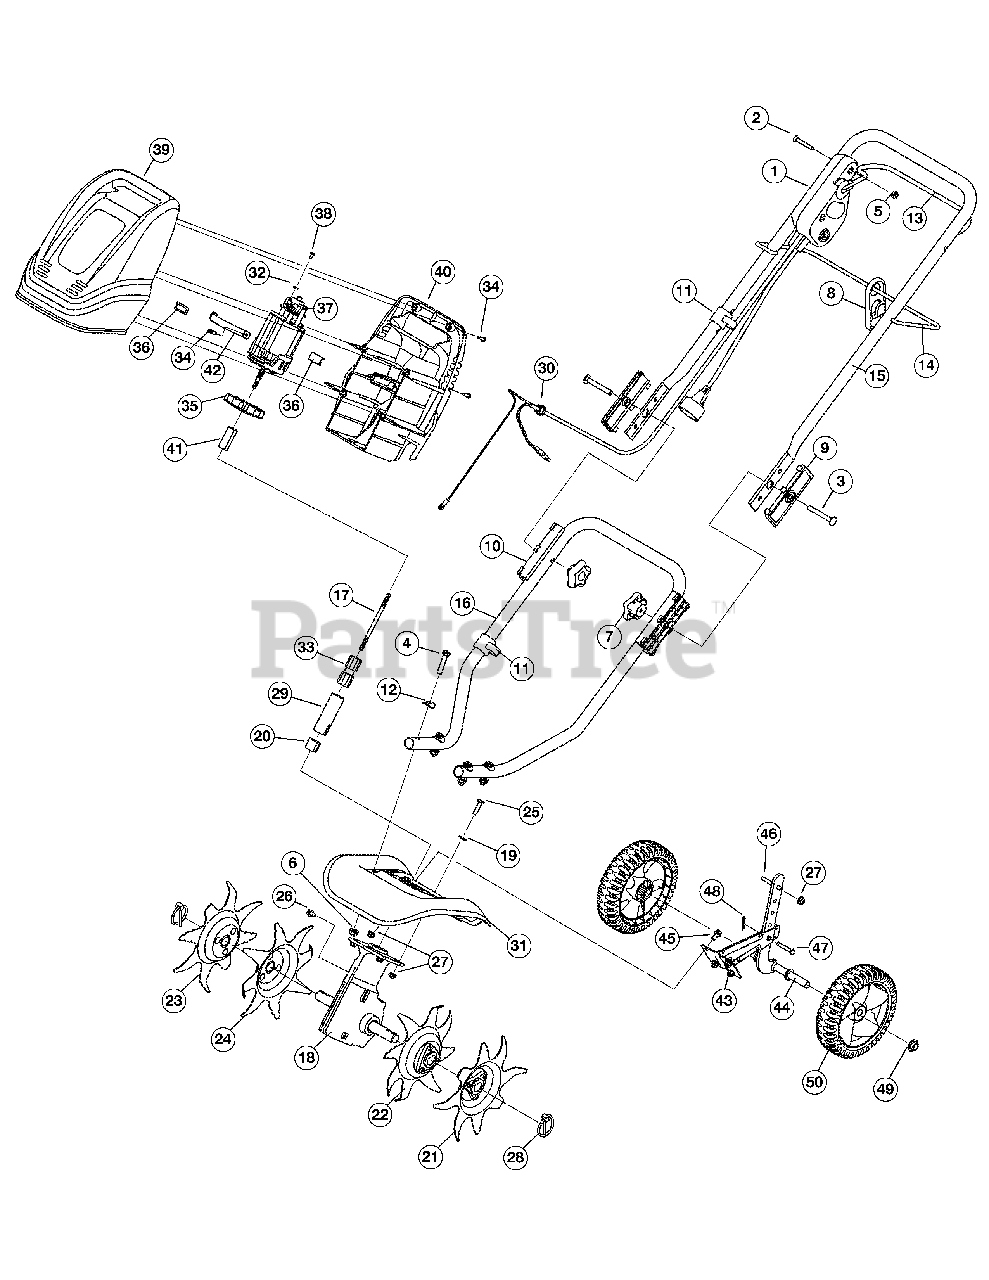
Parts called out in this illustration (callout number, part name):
1	Switch Assembly
2	Screw
4	Screw
5	Nut
7	Knob
9	Upper Handle Insulator
10	Lower Handle Insulator
11	Cable Guide
12	Saddle Washer
15	Upper Handle
17	Flex Shaft
18	Gearbox
19	Washer
20	Sleeve
21	Outer Tine Assembly
22	Inner Tine Assembly
23	Outer Tine Assembly
24	Inner Tine Assembly
25	Screw
26	Bolt
28	Lynch Pin
29	Boom Tube
30	Cord Bushing
31	Tine Shield
32	Lock Washer
33	Flex Tube Assembly
34	Screw
35	Fan
36	Motor Pad
37	Motor Assembly
39	Front Motor Cover
40	Rear Motor Cover
41	Motor Hub
42	Motor Strap
43	Bracket Assembly
44	Wheel Support Bracket Assembly
46	Belt Guard Pin
47	Clevis Pin
48	Cotter Pin
49	Push Cap
50	Wheel
